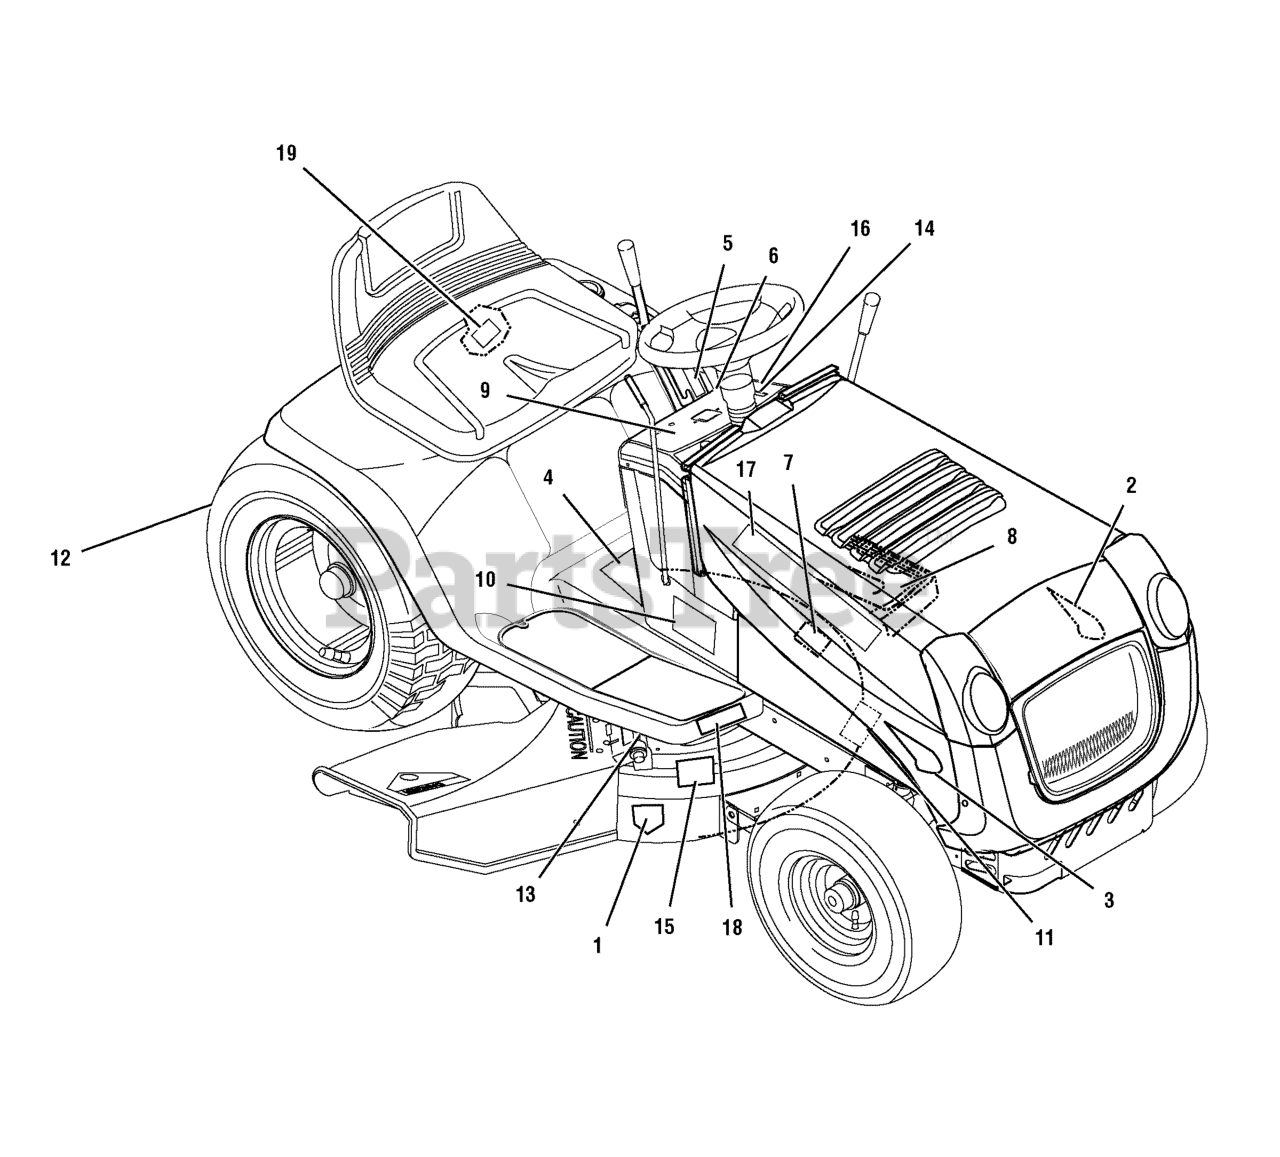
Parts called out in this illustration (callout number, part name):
1	DECAL, Cut Fingers Symbol
2	DECAL, 175/107 L.H.
3	DECAL, 175/107 R.H.
4	DECAL, Warning Export
5	DECAL, 7 Position Cut Height
6	DECAL, Deck Level
7	DECAL, No Step Export
8	DECAL, Brake/Clutch Export
9	DECAL, Engage & Park Brake
10	DECAL, B&S Logo
11	DECAL, Heat Shield Warning
12	DECAL, Warning Load Limit Export
13	DECAL, Warning Pinch Point
14	DECAL, Throttle Single with Choke
15	DECAL, 100db Export
16	DECAL, Gas Gauge
17	DECAL, Sentinel by Murray R.H. & L.H.
18	DECAL, Hydro Drive
19	DECAL, Auto Drive Dump Valve
